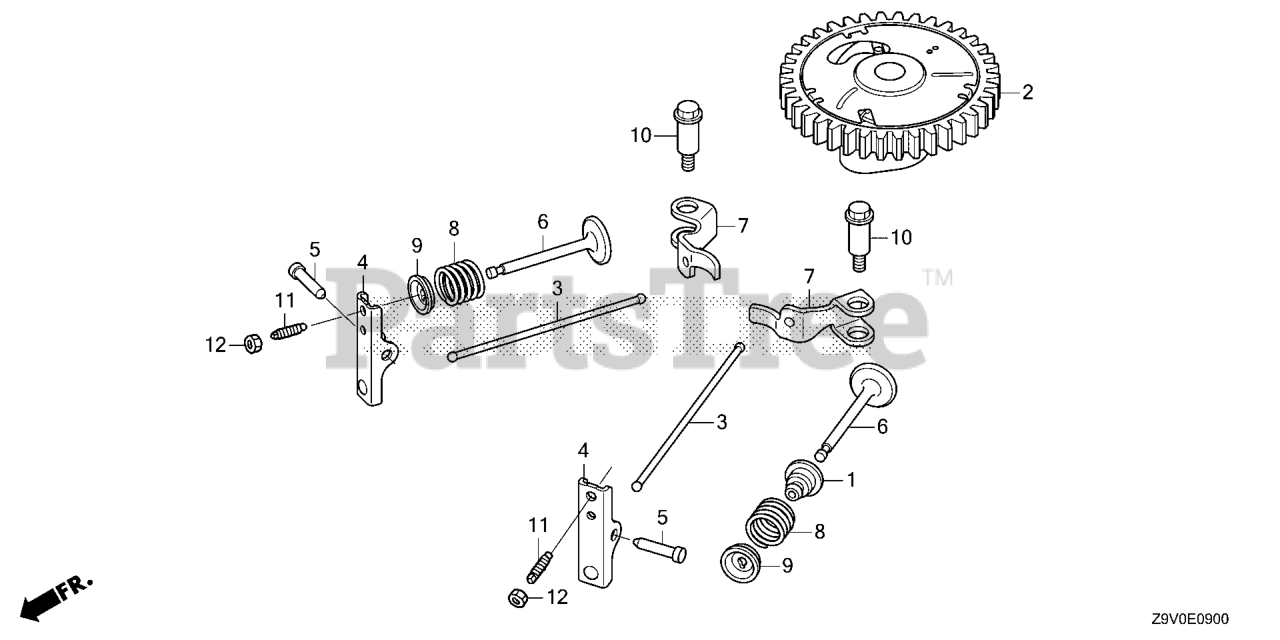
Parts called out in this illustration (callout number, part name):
1	SEAL, VALVE STEM
2	CAMSHAFT ASSY.
4	ARM, VALVE ROCKER
5	SHAFT, ROCKER ARM
6	VALVE, IN. (IN./EX.)
7	LIFTER, VALVE
8	SPRING, VALVE
9	RETAINER, VALVE SPRING
10	BOLT, SHOULDER (6MM)
11	SCREW, TAPPET ADJUSTING
11	SCREW, TAPPET ADJ.
12	NUT, TAPPET ADJUSTING
12	NUT, TAPPET ADJ.
